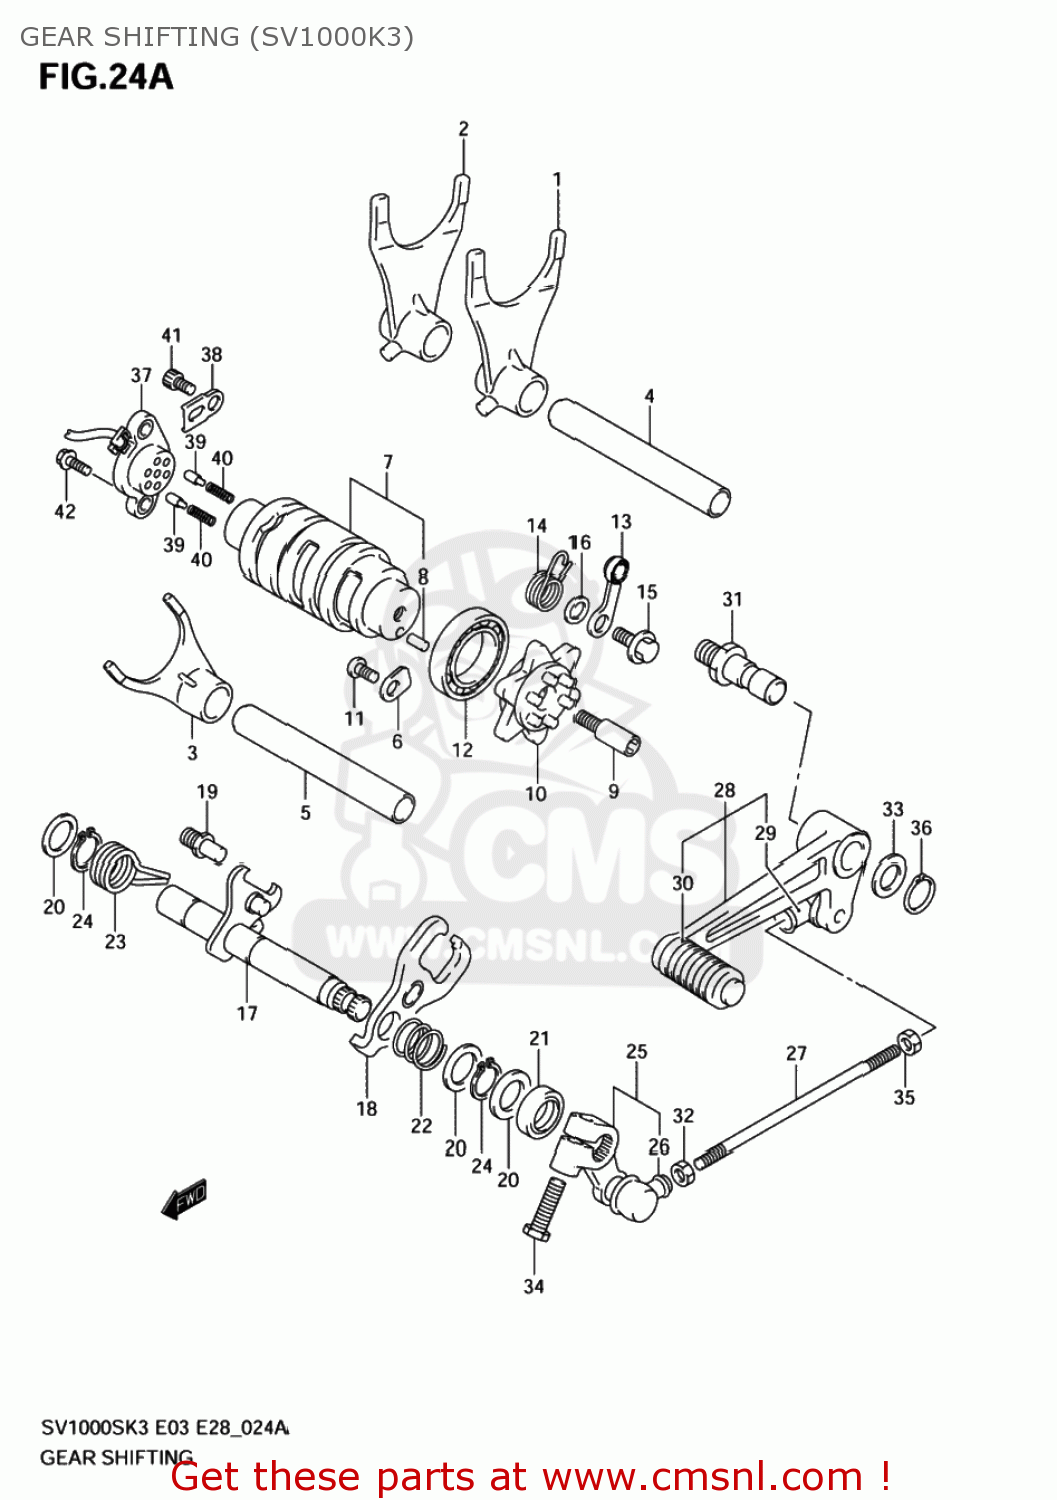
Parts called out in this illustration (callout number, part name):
1	FORK,GEAR SHIFT
2	FORK,GEAR SHIFT NO.1
3	FORK,GEAR SHIFT NO.3
4	SHAFT,GEAR SHIFT FORK
5	SHAFT,GEAR SHIFT FORK
6	RETAINER
7	CAM,GEAR SHIFT
8	PIN
9	PIN,SHIFT CAM DRIVEN GEAR
10	PLATE,GEAR SHIFT CAM
11	BOLT(6X12)
12	BEARING
13	STOPPER,SHIFT CAM
14	SPRING,GEAR SHIFT CAM STOPPER
15	BOLT(6X14.3)
16	WASHER
17	SHAFT,GEAR SHI
18	PLATE,GEAR SHIFT CAM DRIVE
19	STOPPER,GEAR SHIFT ARM
20	SHIM(14X22X1)
21	SEAL,OIL(14X22X6)
22	SPRING
23	SPRING
24	CIRCLIP
25	ARM,GEAR SHIFT LINK
26	COVER,DUST
27	ROD,GEAR SHAFT LINK
28	LEVER ASSY,GEAR SHIFT
29	COVER,DUST
30	RUBBER,GEAR SHIFT PEDAL
31	SHAFT,GEAR SHIFT LEVER
32	NUT
33	WASHER(12.5X20X1)
34	BOLT
35	NUT
36	CIRCLIP,12 MM
37	BASE ASSY,GEAR SHIFT TERMINAL
38	CLAMP,GENERATOR LEAD WIRE
39	PIN(5X15.5)
40	SPRING
41	BOLT
42	BOLT
